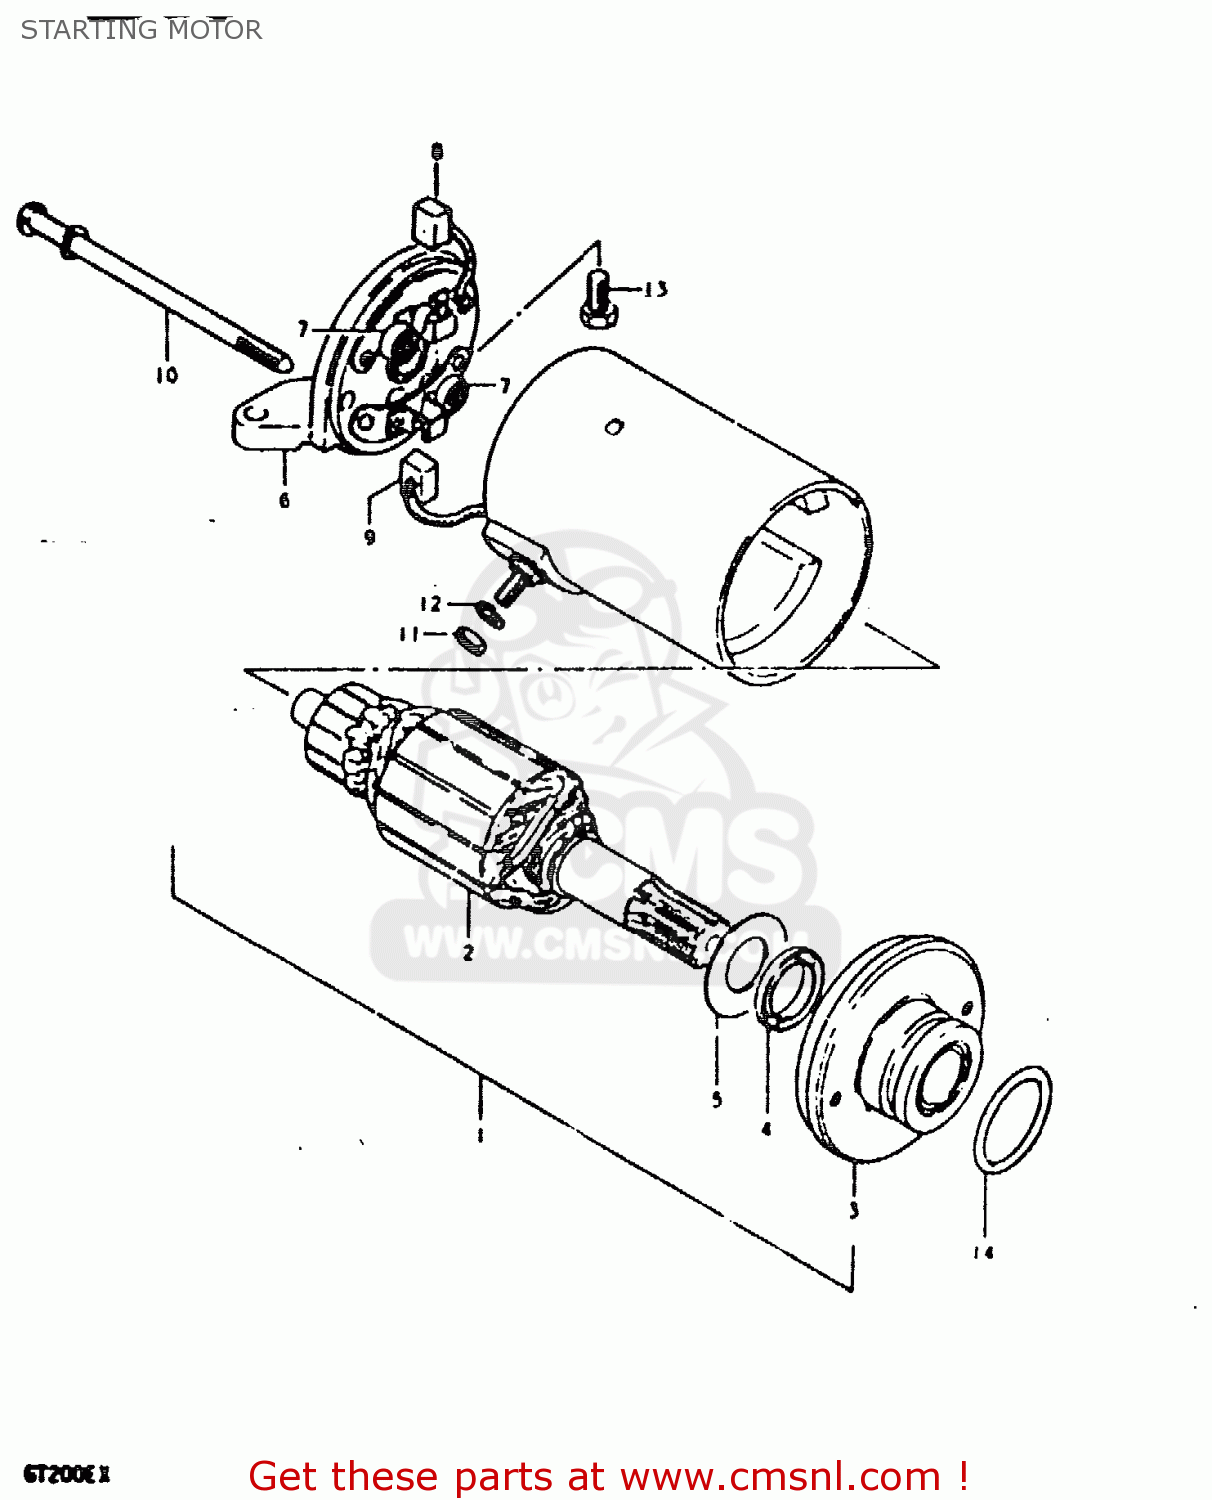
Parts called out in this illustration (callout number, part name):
1	MOTOR ASSY, STARTING
2	ARMATURE
3	HOUSING, DRIVE
4	SEAL,OIL
5	RING,SNAP
6	HOUSING, COMMUTATOR END
7	SPRING
8	BRUSH(-)
9	BRUSH TERMINAL SET
10	BOLT,STARTING MOTOR HOUSING
11	NUT
12	LOCK WASHER
13	BOLT
14	O RING(D:2,ID:24.5)
